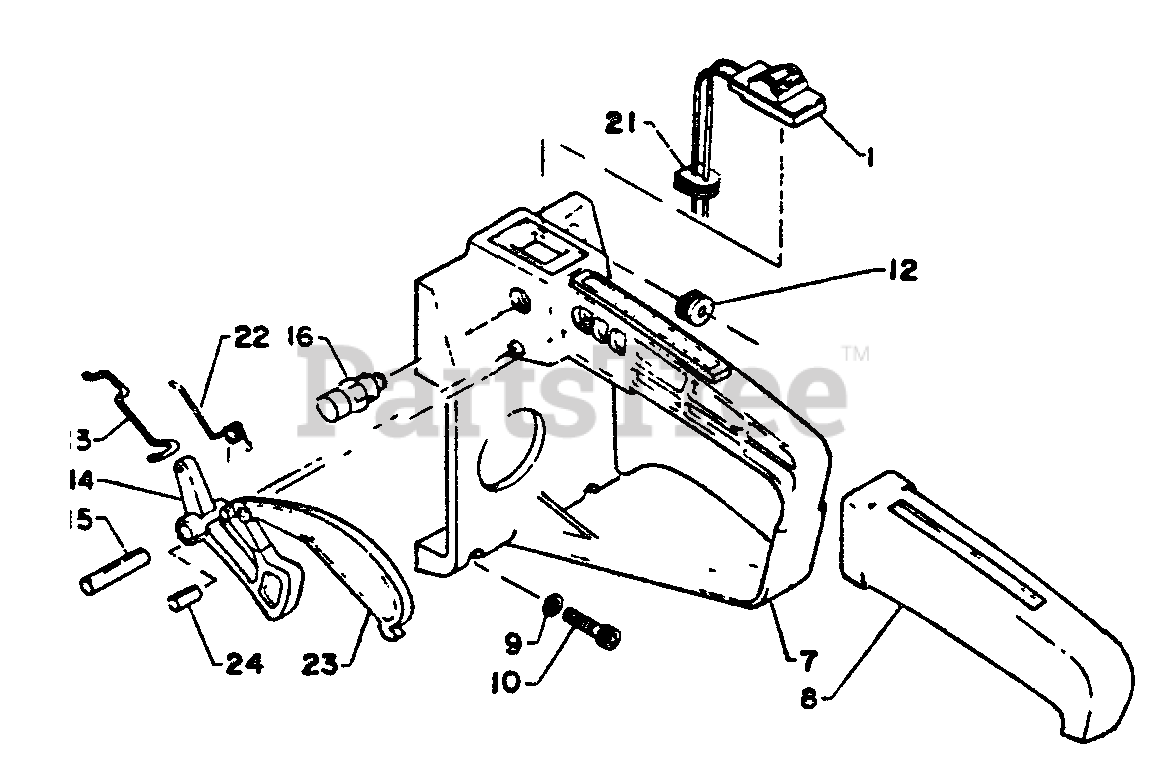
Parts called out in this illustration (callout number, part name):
1	IGNITION SWITCH ASSY
7	RIGHT HANDLE
8	RIGHT HANDLE RUBBER
9	WASHER 4 MM
10	SCREW - 4×18
13	ROD, THROTTLE
14	TRIGGER, THROTTLE
15	PIN, SPRING 5×25
16	LATCH, THROTTLE
22	SPRING, LOCKOUT RETURN
23	LOCKOUT, THROTTLE
24	PIN, SPRING
